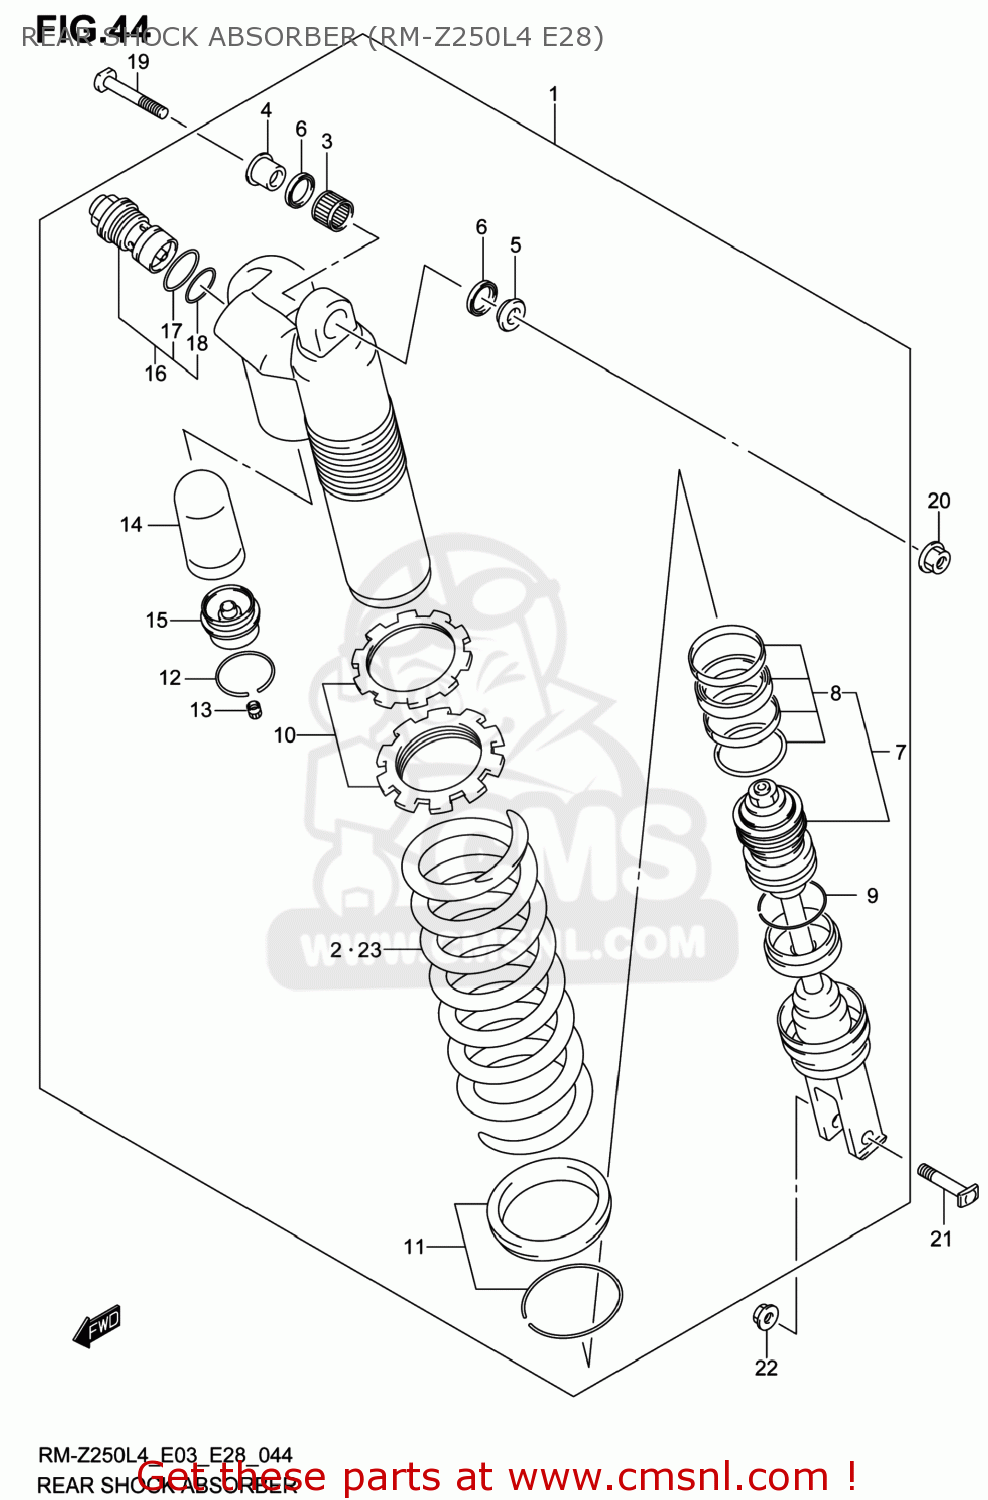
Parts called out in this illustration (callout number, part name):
1	ABSORBER ASSY,RR SHOCK(RED)
2	SPRING(K:5.5)
3	BEARING(16X22X12)
4	SPACER,UPPER BRG,R
5	SPACER,UPPER BRG,L
6	SEAL,OIL(16X22X2.5)
7	ROD,PISTON
8	O RING SET
9	RING,STOPPER
10	ADJUSTER SET
11	SPRING SEAT SET
12	RING,STOPPER
13	CAP,AIR VALVE
14	BLADDER
15	CAP,CHAMBER
16	BOLT,PLUG
17	O RING
18	O RING
19	BOLT,RR SHOCK ABSORBER UPR
20	NUT
21	BOLT,RR SHOCK ABSORBER LWR
22	NUT
23	SPRING,RR(K=5.3)
